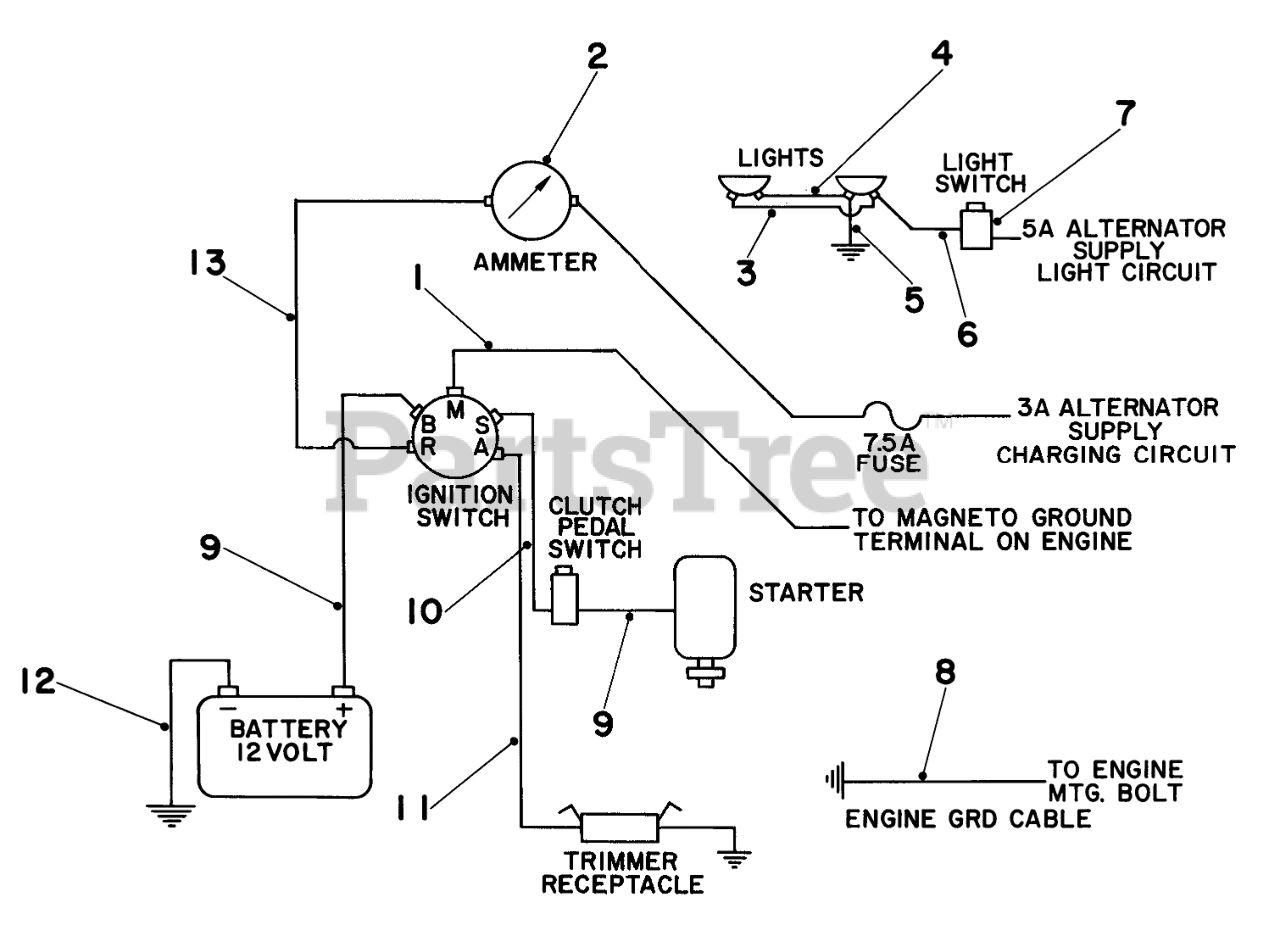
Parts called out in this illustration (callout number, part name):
1	Wire Switch to Battery
2	Ammeter
3	Wire 960
4	Wire 960
5	Wire Assy.-Red
6	Wire Assy.
7	Light Switch
8	ENG-GROUND WIRE ASM
9	Wire Assy.
10	Wire Pedal Switch to Starter Switch
11	Wire Assembly
12	Wire Assembly
13	Wire Assy. Ammeter to Switch
